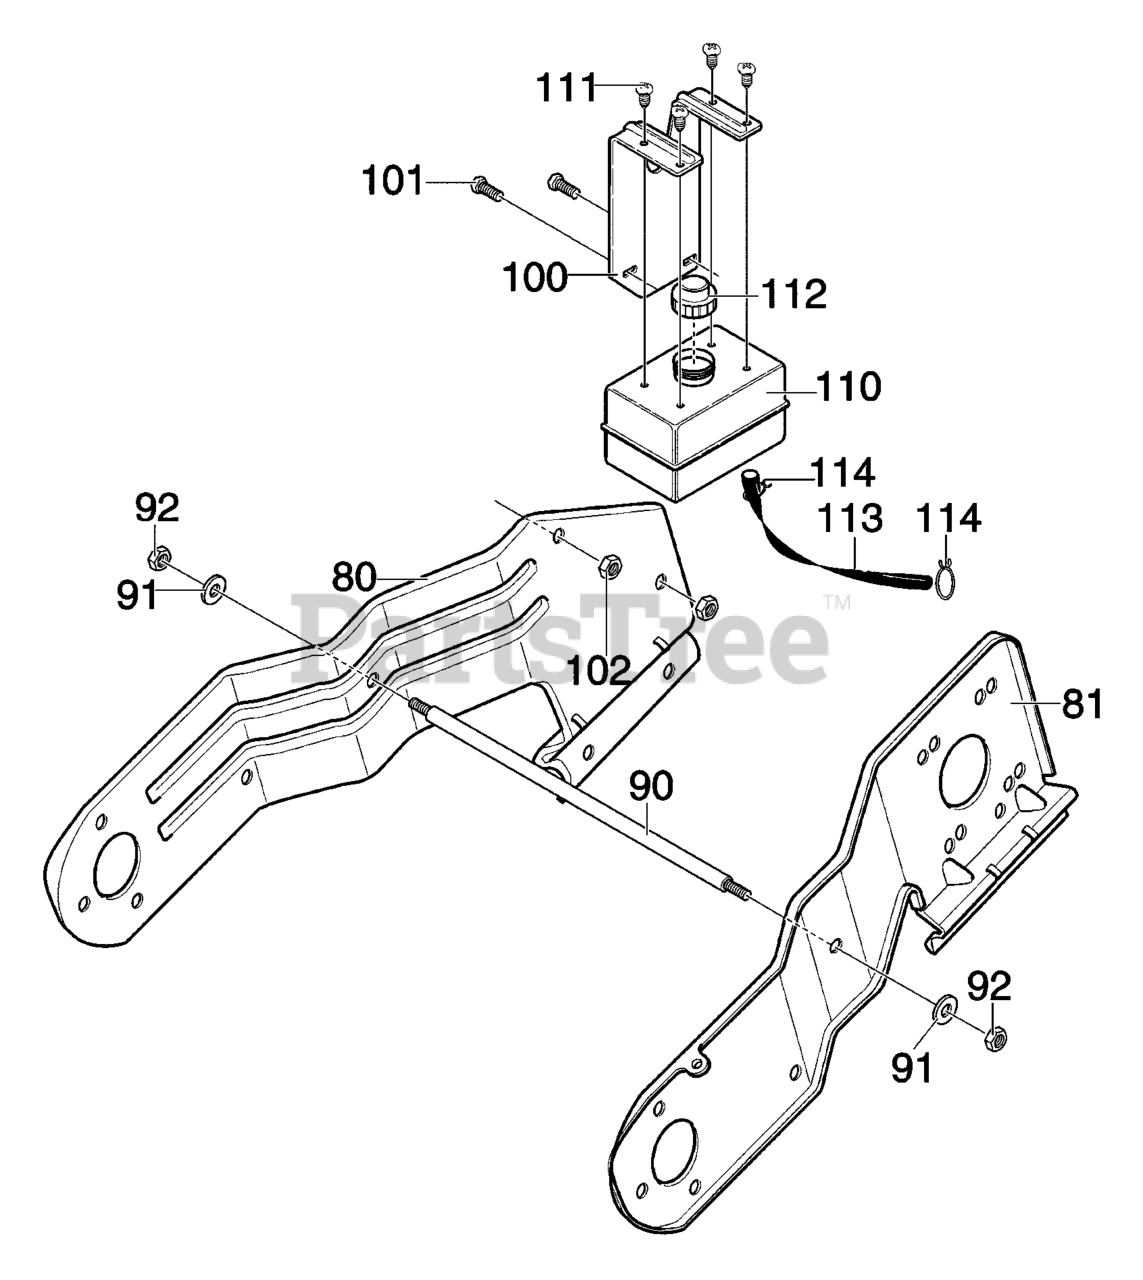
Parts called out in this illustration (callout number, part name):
80	FRAME, RIGHT
81	FRAME, LEFT
90	ROD, SUPPORT
91	WASHER
92	NUT, 3/8-16
100	BRACKET, GAS TANK
101	SCREW, 1/4-20X.75
102	NUT, 1/4-20
110	TANK, FUEL
112	CAP, GAS
113	TUBING, 11.5 IN.
114	CLAMP, HOSE
